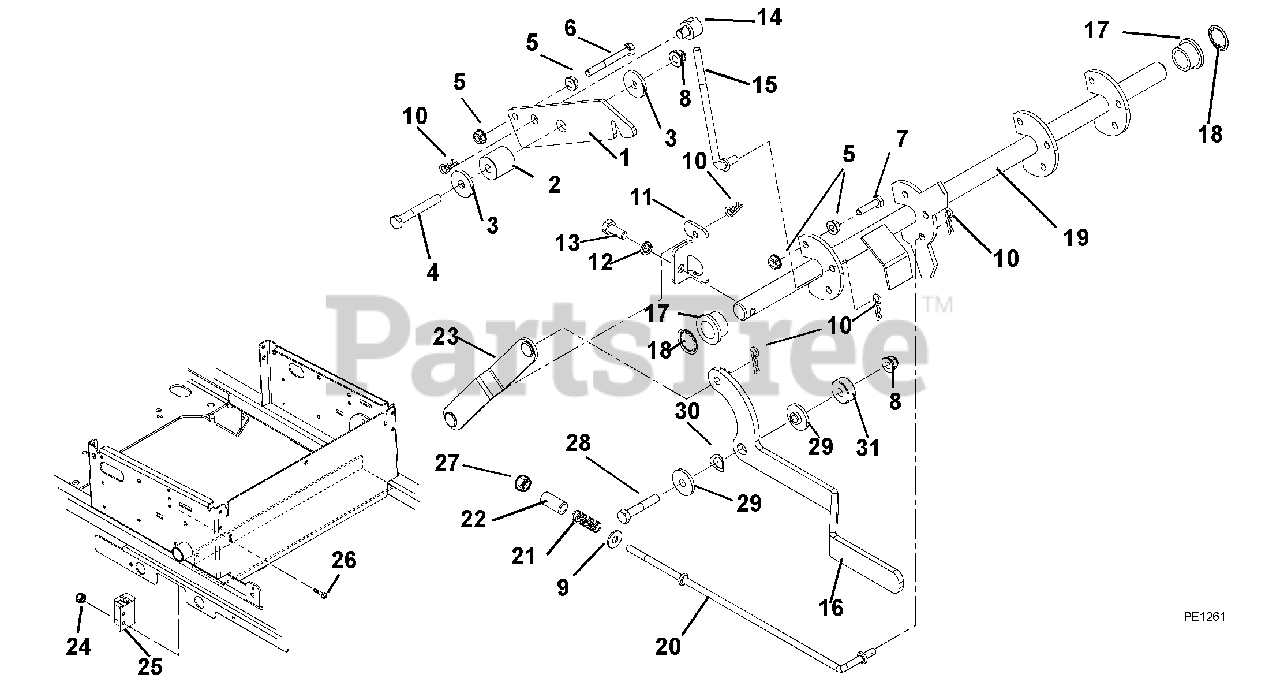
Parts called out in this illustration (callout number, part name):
1	Latch, Neutral
3	Washer, Flat Steel .344 x 1.125 x .135
4	Bolt, Hex .31-18 x 2.25 Grade 5
5	Nut, Locking Flange .250-20
6	Bolt, Hex .25-20 x 2.25 Grade 5
7	Bolt, Hex .25-20 x 1.00 Grade 5
8	Nut, Flange Nyloc .31-18
9	Washer, Flat Steel .312 x .734 x .065
10	Pin, Hair Internal .08 x .18 x 1.18
11	Crank, Parking Brake
12	Washer, Locking .31 x .078 Regular
13	Bolt, Hex .31-18 x 1.00 Grade 5
14	Trunnion, Brake
15	Brake, Link
16	Handle, Parking Brake
17	Bushing, Flanged .750 x 1.000 x .625 x 1.250
18	Push Nut, .745 Shaft
19	Weldment, Brake Shaft
20	Link, Brake
21	Spring, Compression
23	Link, Parking Brake
24	Nut, Locking Nylon 10-24 with Insert
25	Switch, Double Pole
26	Screw, Machine 10-24 x .75
27	Nut, Locking-Nylon .250-20
28	Bolt, Hex .31-18 x 1.75 Grade 5
29	Bushing, Flange .325 x .501 x .250 x 1.120
30	Washer, Wave .50 x .75 x .015 .13
31	Washer, Flat-Steel .38 x .87 x .179
